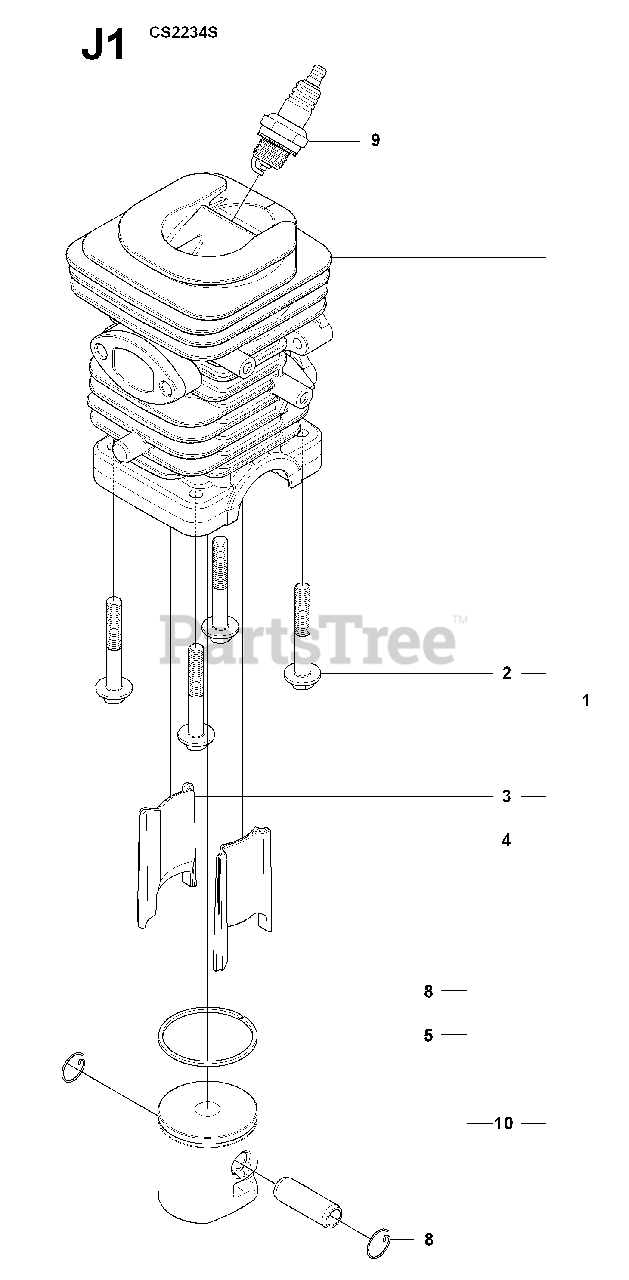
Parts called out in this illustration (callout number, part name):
1	KIT, CYLINDER & PISTON
3	TRANSFER INSERT LEFT
4	TRANSFER INSERT RIGHT
5	PISTON RING
8	C-CLIP,PSTN PIN 36/41
9	SPARK PLUG RCJ7Y
10	PISTON KIT
